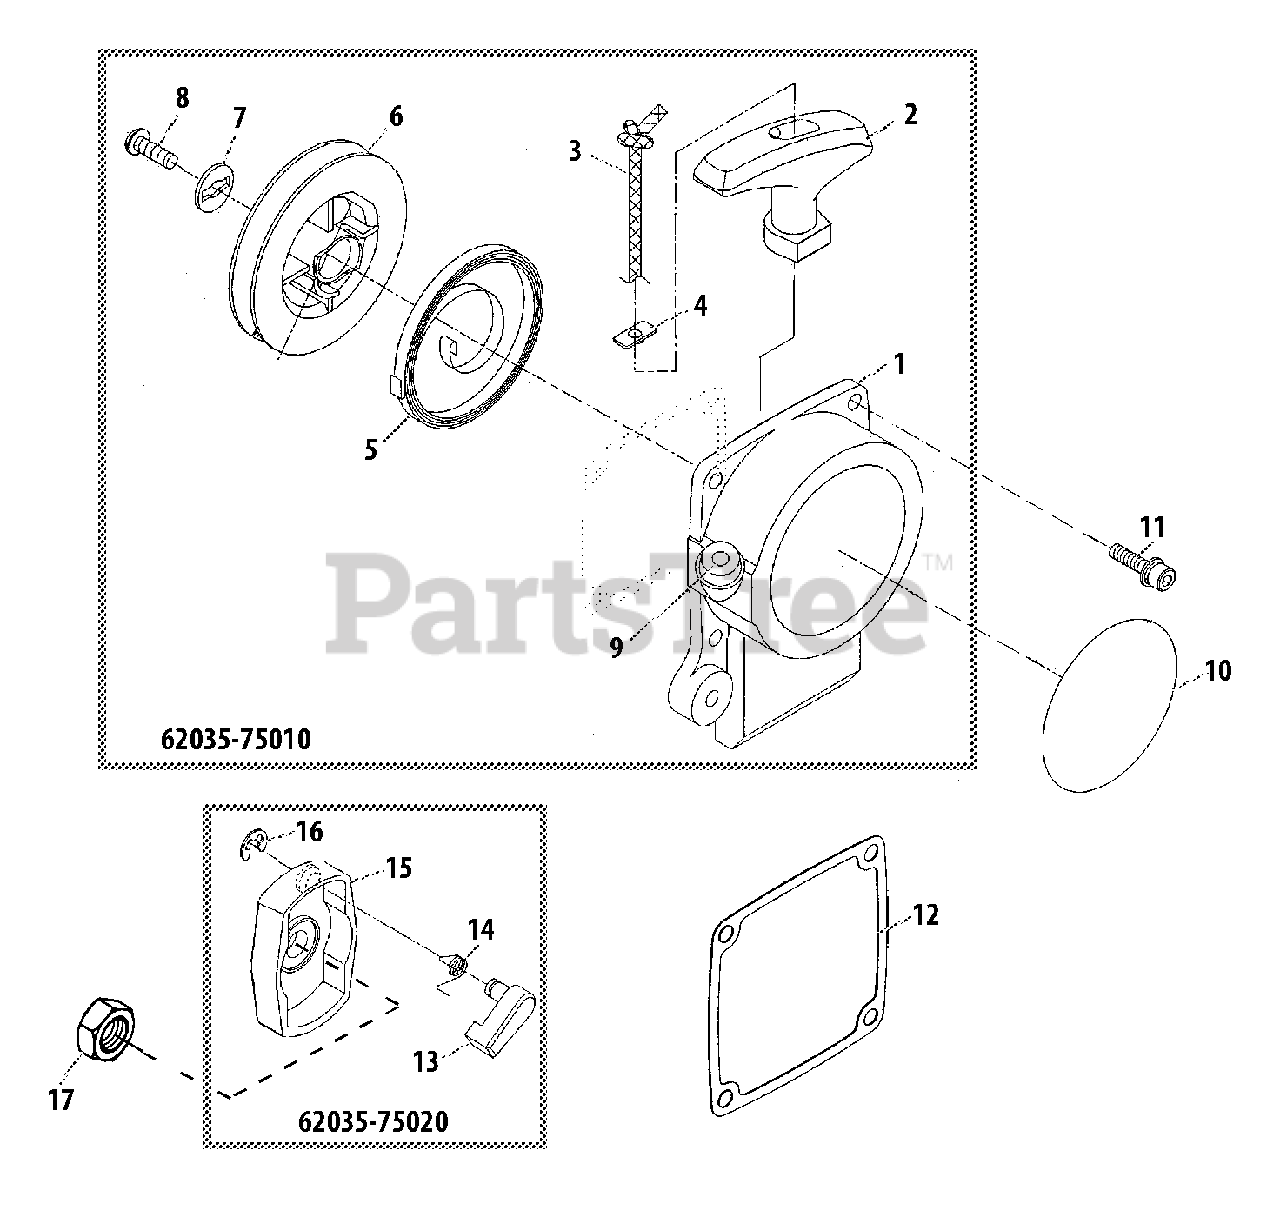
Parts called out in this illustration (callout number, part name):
1	CASE, RECOIL STARTER
2	GRIP, STARTER
3	ROPE
4	RETAINER, ROPE
5	SPRING, RECOIL
6	REEL, ROPE
7	WASHER
8	SCREW 5
9	GUIDE, ROPE
10	LABEL, TRADE
11	BOLT M5×25
12	GASKET, RECOIL STARTER
13	PAWL, STARTER
14	SPRING, RETURN
15	PULLEY, STARTER
16	E-RING 4
17	NUT
62035-75010	STARTER ASSY, RECOIL
62035-75020	PULLEY ASSY, STARTER
